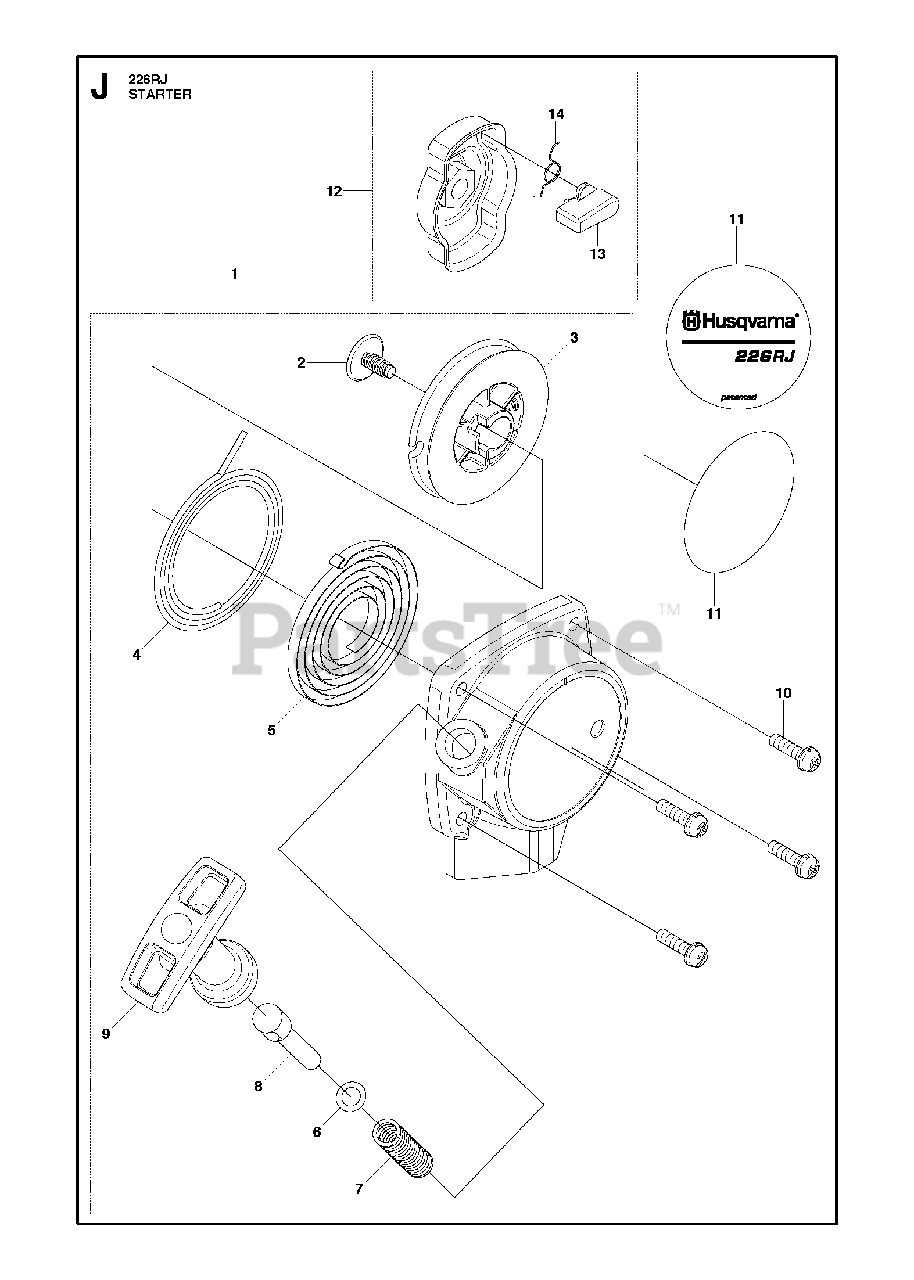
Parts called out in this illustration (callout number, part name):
2	SCREW
3	REEL
4	ROPE
5	SPRING, SPIRAL
6	Washer
7	SPRING
8	COLLAR (RPLS T160075320)
9	KNOB
13	RATCHET
14	SPRING
